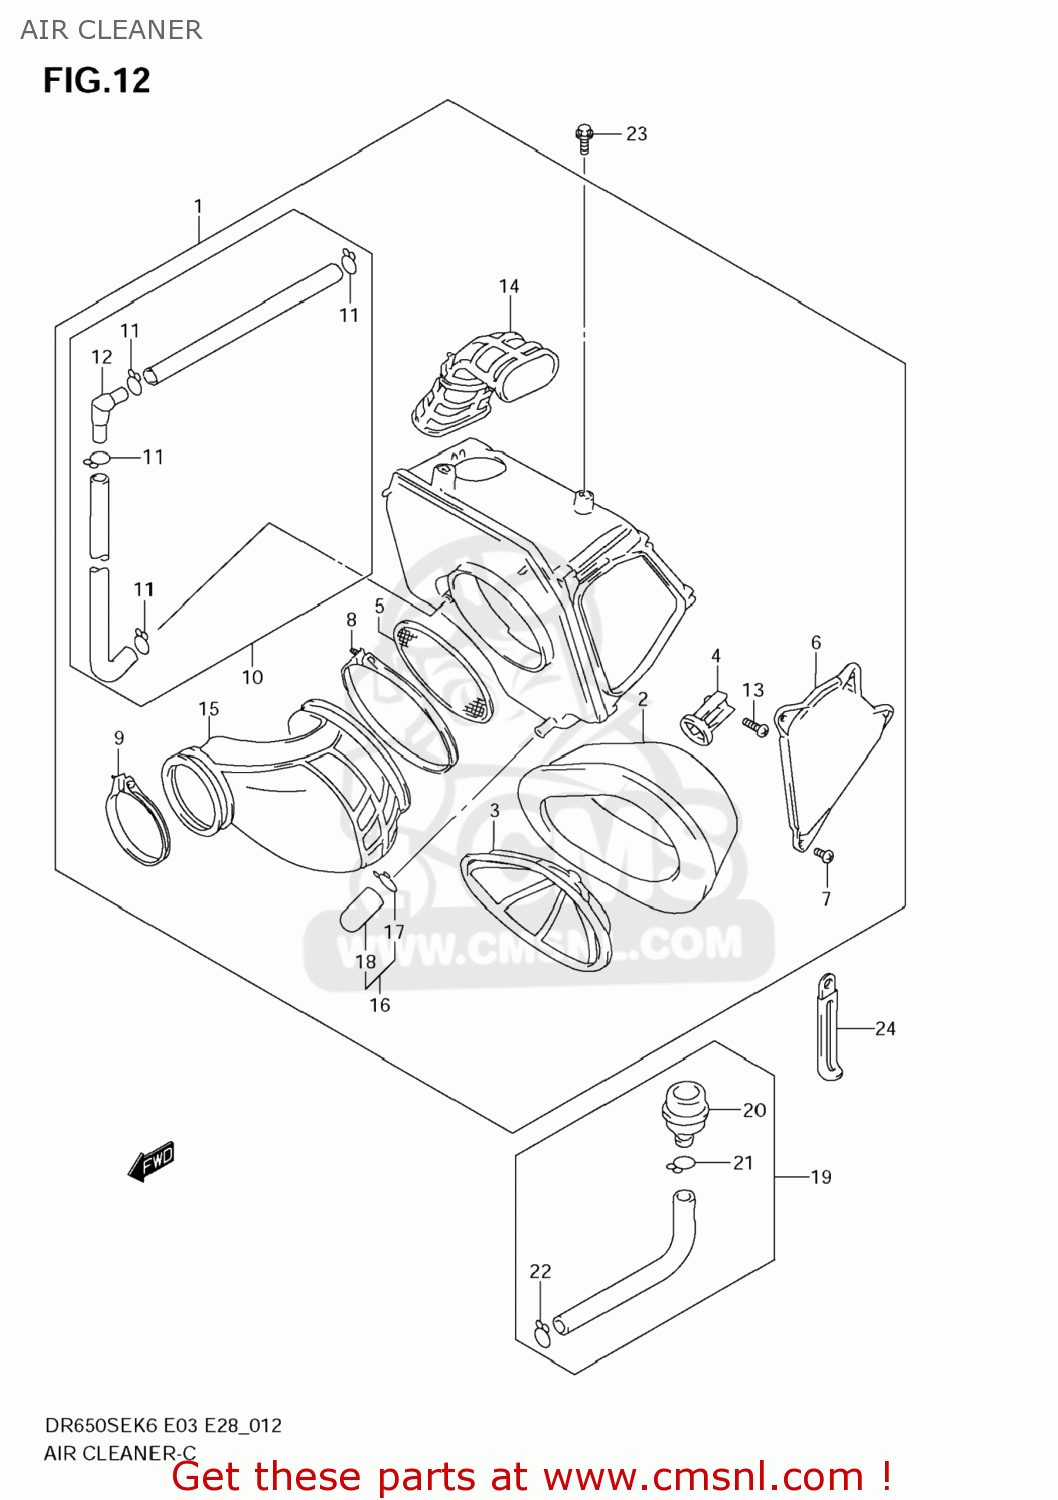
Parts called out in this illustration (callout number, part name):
1	CLEANER ASSY,AIR
2	FILTER
3	HOLDER,FILTER
4	STOPPER,HOLDER
5	TRAP,FRAME
6	CAP,CLEANER
7	SCREW
8	CLAMP,OUTLET TUBE
9	CLAMP
10	TUBE ASSY,BREATHER
11	CLIP
12	JOINT
13	SCREW
14	TUBE,INLET
15	TUBE,OUTLET
16	PLUG ASSY,DRAIN
17	CLIP
18	PLUG
19	CLEANER ASSY,AIR NO.2
20	FILTER,2ND AIR CLEANER
21	CLIP
22	CLIP
23	BOLT
24	CLAMP(L:80)
